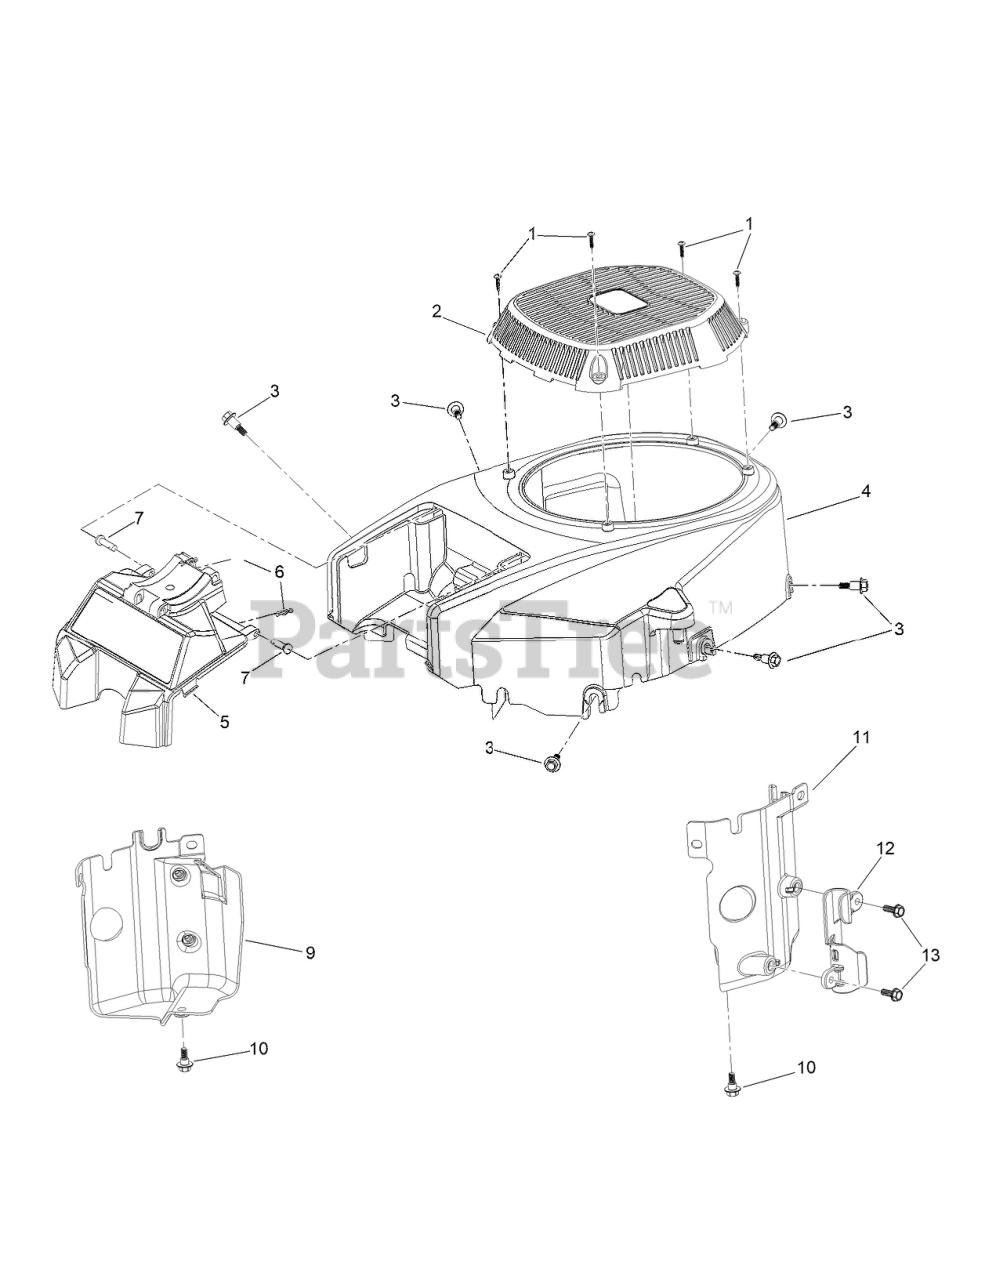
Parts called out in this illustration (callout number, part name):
1	SCREW-PPH, PLASTIC
2	COVER-FAN
3	SCREW-SHOULDER, HWH
4	SHROUD-ENGINE
5	SUPPORT-FILTER
6	PIN-HAIR
9	BAFFLE-AIR, LEFT
10	SCREW-SHOULDER, HHF
11	BAFFLE-AIR, RIGHT
12	CLEAT-HOSE
13	SCREW-HHF
